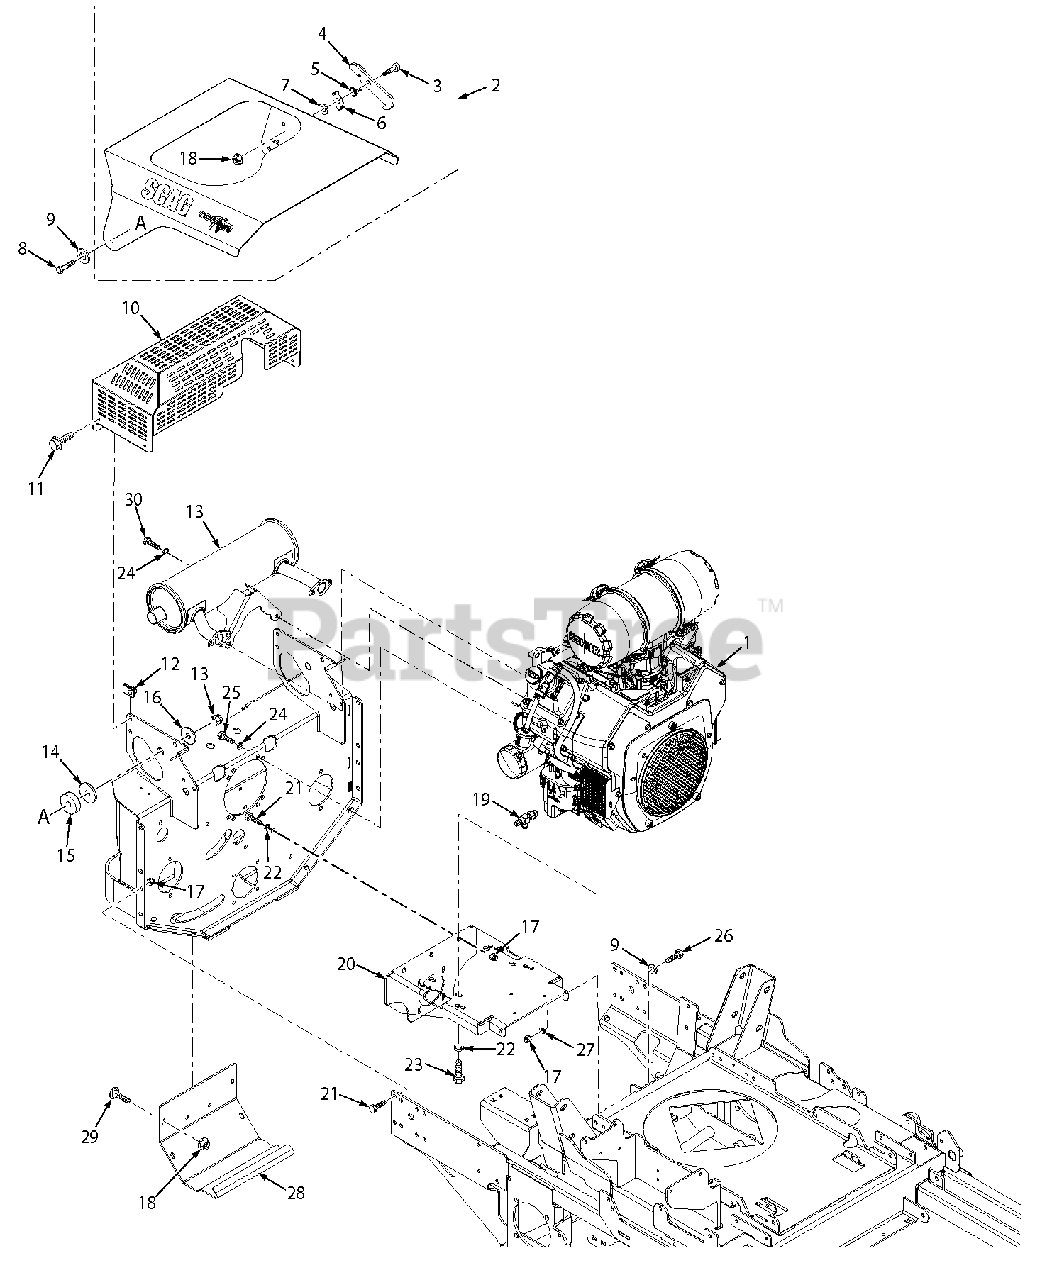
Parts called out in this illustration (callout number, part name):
1	Engine, 26EFI - Kohler
1	Engine, 35BV - Briggs & Stratton
2	Hood Assy., STTII (EFI)
2	Hood Assy., STTII (35BV)
3	Bolt, Shoulder 3/8-1/2
4	Latch, Hood
5	Spring, Hood
6	Lock, Hood
7	Flatwasher, 3/8-.406 x .812 x .065
8	Bolt, Hex Head 3/8-16 x 1-3/4"
9	Flatwasher, 3/8-.391 x .938 x .105
10	Guard, Muffler
11	Bolt, Hex Head Serrated Flange 1/4-20 x 3/4"
12	U-Nut,. 1/4-20
13	Muffler, 26EFI - Kohler
13	Muffler, 35BV - Briggs & Stratton
14	Disc, Anti-Friction
15	Spacer, Hood
16	Flatwasher, 3/8-.406 x 1.50 x 7 Gauge
17	Nut, Elastic Stop 3/8-16
18	Nut, Serrated Flange 5/16-18
19	Oil Drain, 35BV - Briggs & Stratton
20	Plate Weldment, Engine Mounting
21	Bolt, Hex Head 3/8-16 x 1"
22	Lockwasher, 3/8
22	Flatwasher, 5/16-.375 x .875 x .083 (35BV)
23	Bolt, Hex Head 3/8-16 x 1-3/4" (EFI)
23	Bolt, Hex Head 5/16-18 x 2-1/2" (x3) (35BV)
23	Bolt, Hex Head 5/16-18 x 2-1/2" (35BV)
23	Nut, Serrated Flange 5/16-18 (35BV)
24	Lockwasher, 3/8"
25	Bolt, Hex Head 3/16-1"
26	Bolt, Hex Head 3/8-16 x 1-1/4"
27	Lockwasher, 3/8"
28	Cover, Rear
29	Bolt, Carriage 5/16-18 x 3/4"
30	Bolt, Hex Head 3/8-16 x 1"
